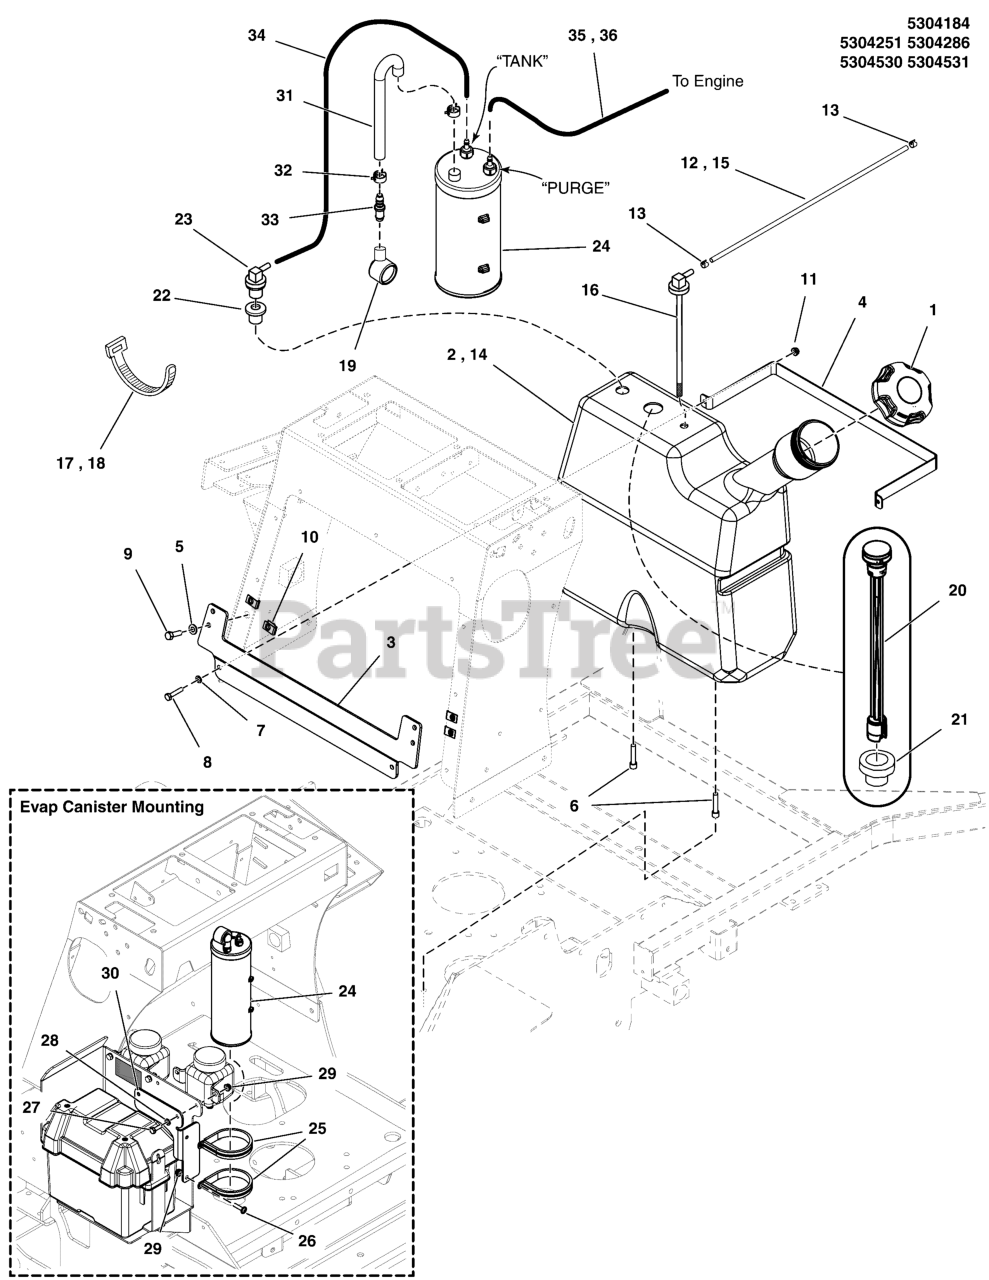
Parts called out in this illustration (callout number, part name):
1	FUEL CAP, 3.25", MANAGED VENT, 16"TETHER
2	TANK, FUEL, STAND -ON, 7.75 GALLON
3	PLATE, SRS Z2 TANK MOUNT, 7.75GAL - BLK
4	STRAP, FUEL TANK, STAND ON - BLK
5	WASHER, 5/16" SAE
6	SCREW, SOC HD, 5/16-18 X 1/2
7	WASHER, 1/4 SAE
8	BOLT, 1/4-20 X 1" GD5 CZ
9	BOLT, 5/16-18 X 1 GD5 CZ
10	BODY CLIP, 5/16-18-7GA MATERIAL
11	NUT, 1/4-20 HEX NYLOCK FLANGE
12	HOSE, 1/4" FUEL, 16.00"
13	CLAMP, HOSE, EXTERNAL, 1/2 - RED
14	KIT, LARGE CAPACITY FUEL TANK, SRS Z2
15	HOSE, 1/4" FUEL, 21.00"
16	PICKUP TUBE ASM, FUEL TANK, 16.50"
17	TIE,SELF-LOCKING, 6"
18	TIE,SELF-LOCKING, 6"
19	DUST FILTER, CANISTER
20	GAUGE, FUEL LEVEL, 17.0"
21	GROMMET, FUEL GAUGE
22	GROMMET
23	REMOTE VENT ASSEMBLY
24	CNSTR, CARB, 9 GAL
25	CLAMP, 3" ID, CUSHIONED, STAINLESS
27	BOLT, 1/4-20 X 1" GD5 CZ
28	WASHER, 1/4 SAE
29	NUT, 1/4-20 HEX NYLOCK FLANGE
30	PLATE, CARB CAN, SRSZ2 - BLK
31	HOSE, FORMED, EVAP CANISTER
32	CLAMP, HOSE
33	FITTING, STRAIGHT, 10MMX10MM, PLASTIC
34	HOSE, VAPOR, 5MM ID, 27.00 LG
35	HOSE, VAPOR, 5MM ID, 20.50 LG
36	HOSE, VAPOR, 5MM ID, 45.00 LG
